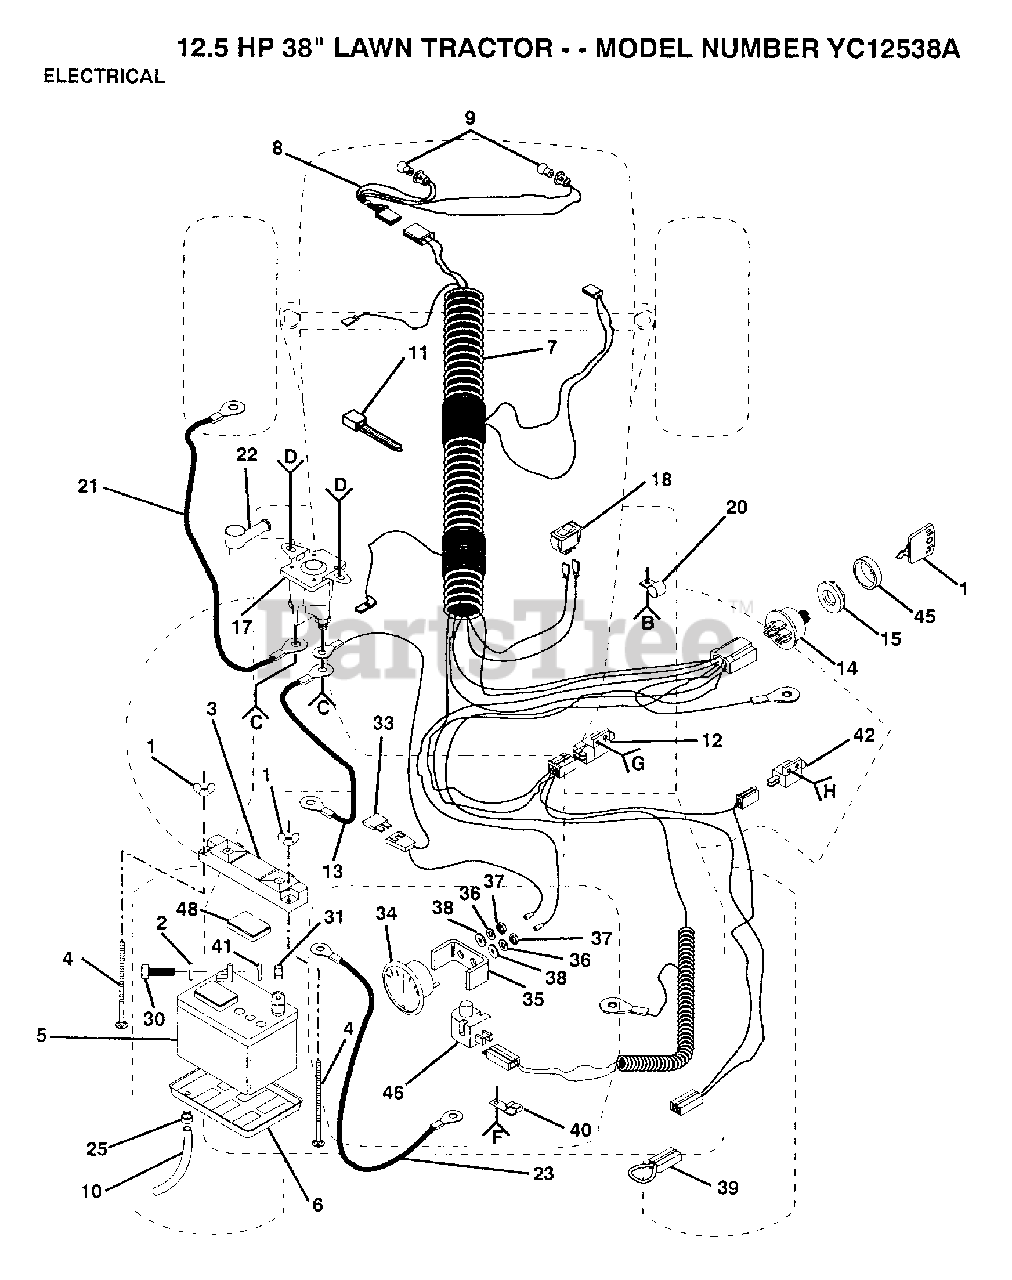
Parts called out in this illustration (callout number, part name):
2	WASHER
4	BOLT
6	"TRAY T, BATTERY"
7	IGNITION HARNESS
11	WIRE TIE
12	SWITCH INTERLOCKT
13	CABLE-BATTERY T
18	SWITCH LT
21	"CABLE T, BATTERY"
23	CABLE T
25	HOSE CLAMP T
30	BOLT LT
33	FUSE HYT
34	AMMETER T
38	WASHER
40	CLIPT
41	LOCKWASHER
42	SWITCH-INTER. GT
46	SWITCH SEAT
48	"CAP,BATTERY "
